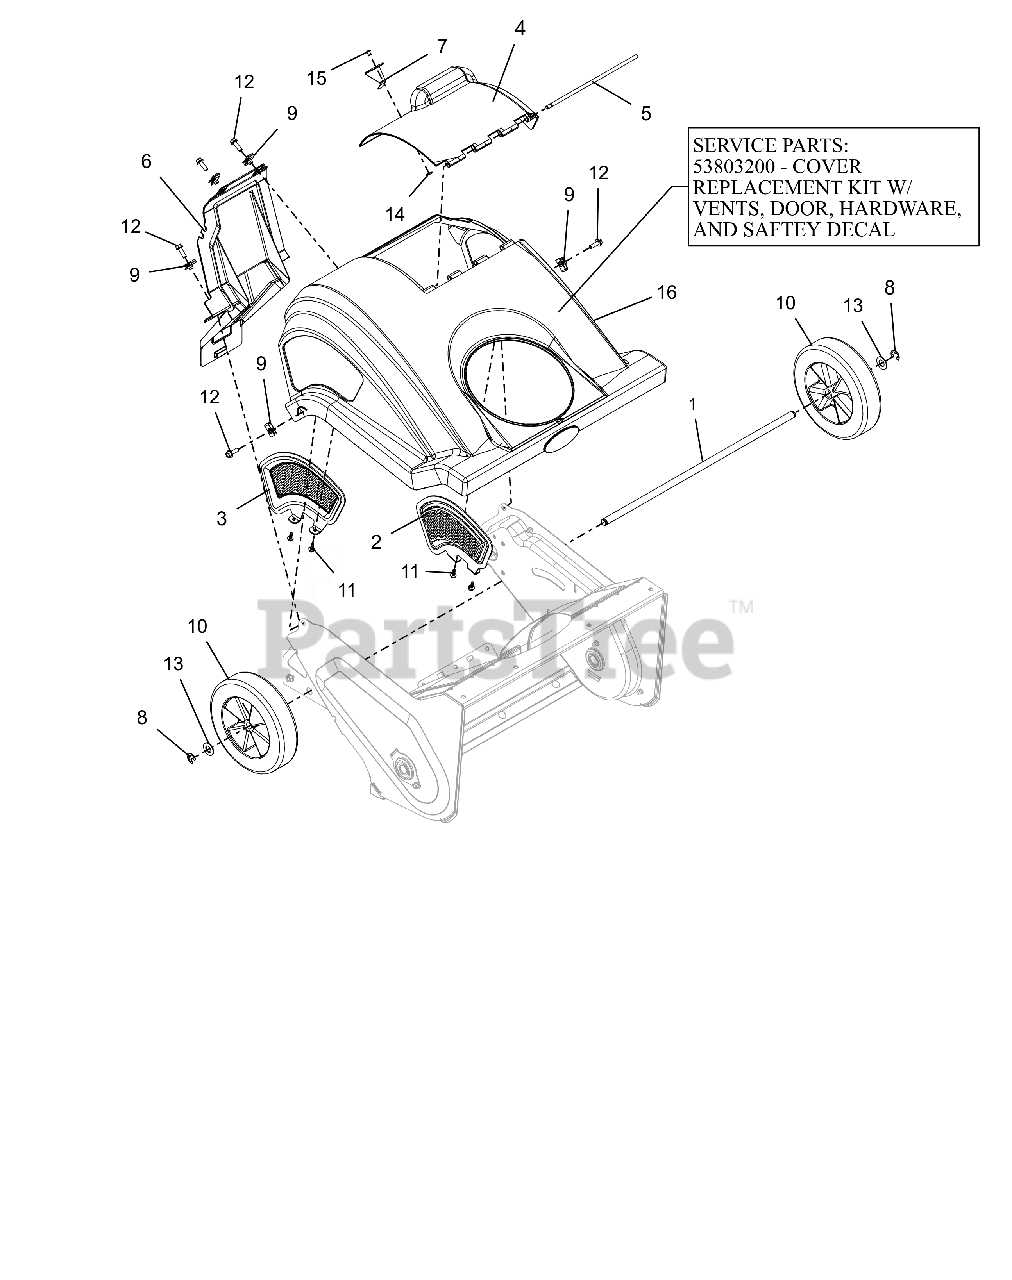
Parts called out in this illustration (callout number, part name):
1	SHAFT, AXLE
2	VENT, COVER LEFT
3	RIGHT VENT, COVER
4	DOOR, COWEL COVER
5	ROD, COVER, SINGLE STAGE
6	KIT, ELECTRIC START BACK PANEL
7	TAB, LATCH
8	RG-RTNG-EXT .500X.042 (E)
9	NUT-RTNR .25-20X.56
10	WHL 7.50" .50 BORE, 1.50 HUB
11	SCR-TAP #10X.50 BOSS INDHXHD
12	BLT-HEX .25-20X.75 HWH YZ GR5
13	WSHR-FL-STL.531X1.00X.063 YWZC
14	WSHR-FL-STL .196X.500X.06 YZ
15	RVT-POP .187 YZ
16	KIT, COWL REPLACEMENT
